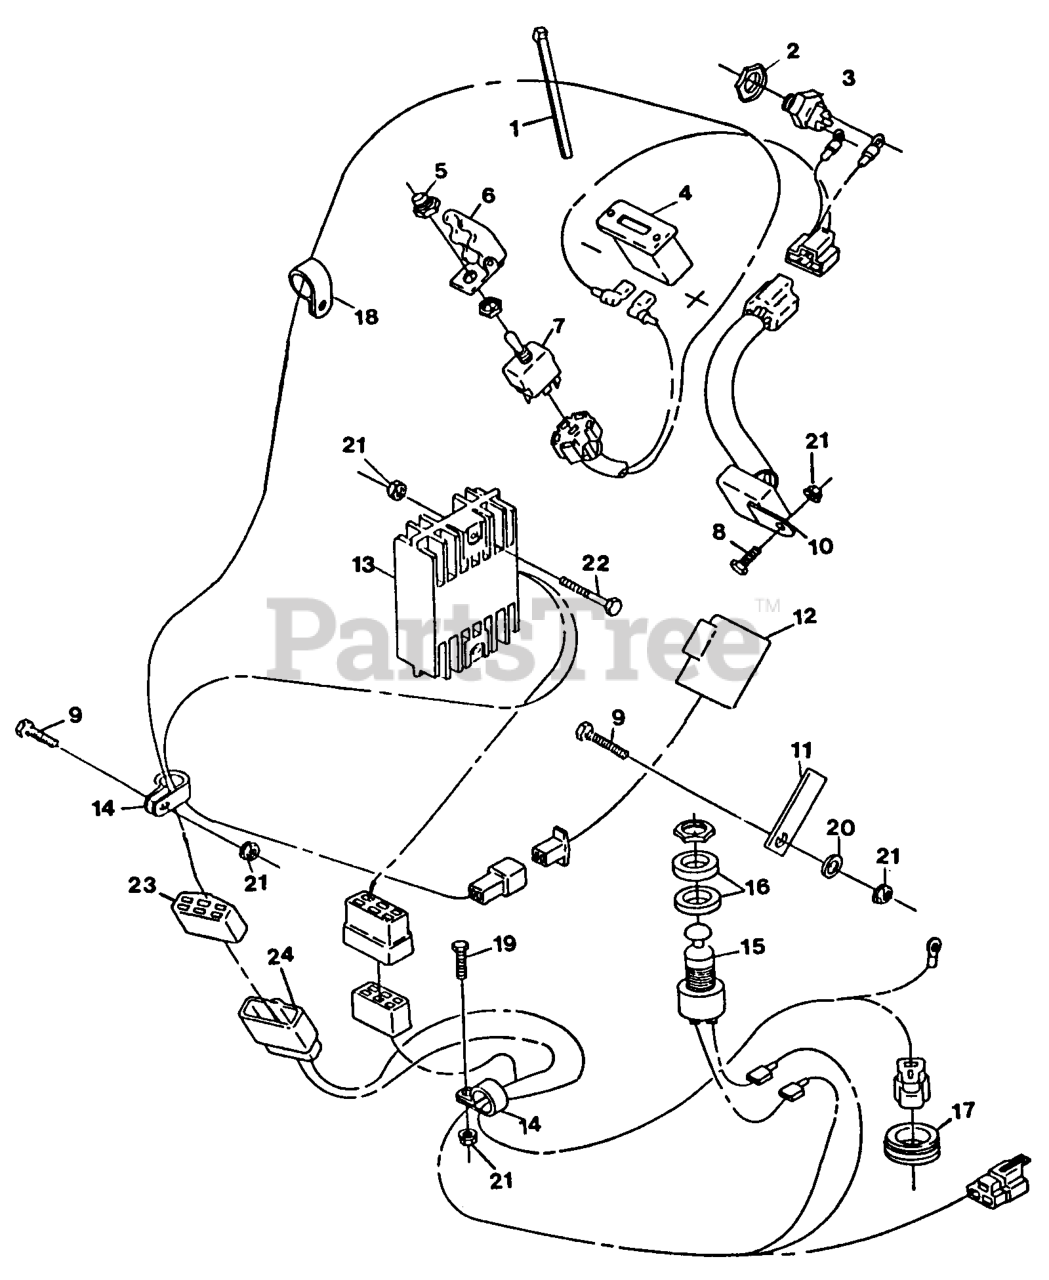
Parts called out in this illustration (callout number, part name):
1	TIE-PLASTIC
3	SWITCH,OPERATOR CNTRL
4	METER-HOUR
5	BOOT-SWITCH, TOGGLE
14	CLIP-LOOM
15	SWITCH,PUSH BUTTON
17	GROMMET
18	CLIP-LOOM
